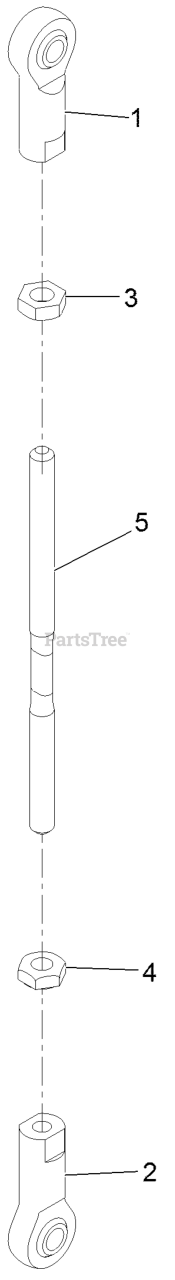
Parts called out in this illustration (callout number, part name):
1	ROD END-BALL JOINT
2	JOINT-BALL, LH
3	NUT-JAM
4	NUT-JAM
